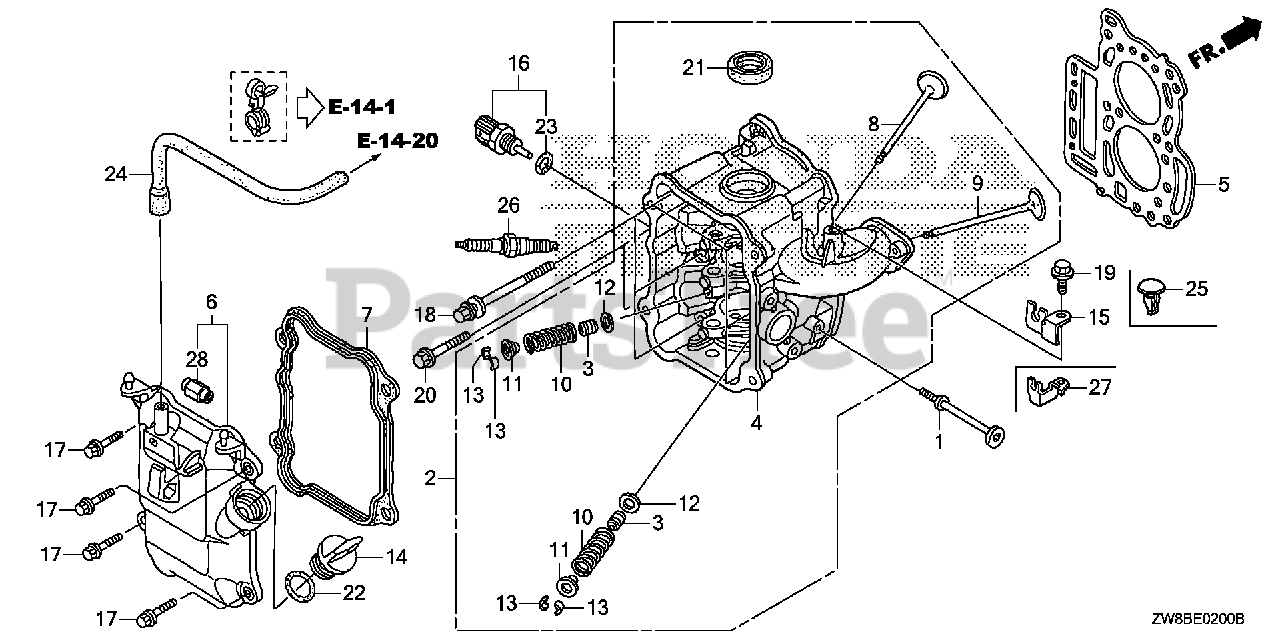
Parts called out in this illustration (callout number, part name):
1	STOPPER, ENGINE SIDE
3	SEAL, VALVE STEM (NOK)
4	CYLINDER HEAD (000) *NH8* (DARK GRAY)
5	GASKET, CYLINDER HEAD
6	COVER, HEAD
7	GASKET, HEAD COVER
8	VALVE, IN.
9	VALVE, EX.
10	SPRING, VALVE
11	RETAINER, VALVE SPRING
12	SEAT, VALVE SPRING
13	COTTER, VALVE
14	CAP, OIL
15	HOLDER, CABLE
16	SENSOR ASSY., WATER TEMPERATURE
17	BOLT, FLANGE (6X22)
18	BOLT, FLANGE (8X83)
19	BOLT, FLANGE (6X14) (CT200)
20	BOLT, FLANGE (8X40)
21	OIL SEAL (20X32X6)
22	O-RING (26X2.7)
23	O-RING (9.5X1.5) (HONDA KIKAKI)
24	TUBE, BREATHER
26	SPARK PLUG (CR5EH-9) (NGK)
26	SPARK PLUG (U16FER9) (DENSO)
27	HOLDER, CABLE
28	NUT, INSERT
